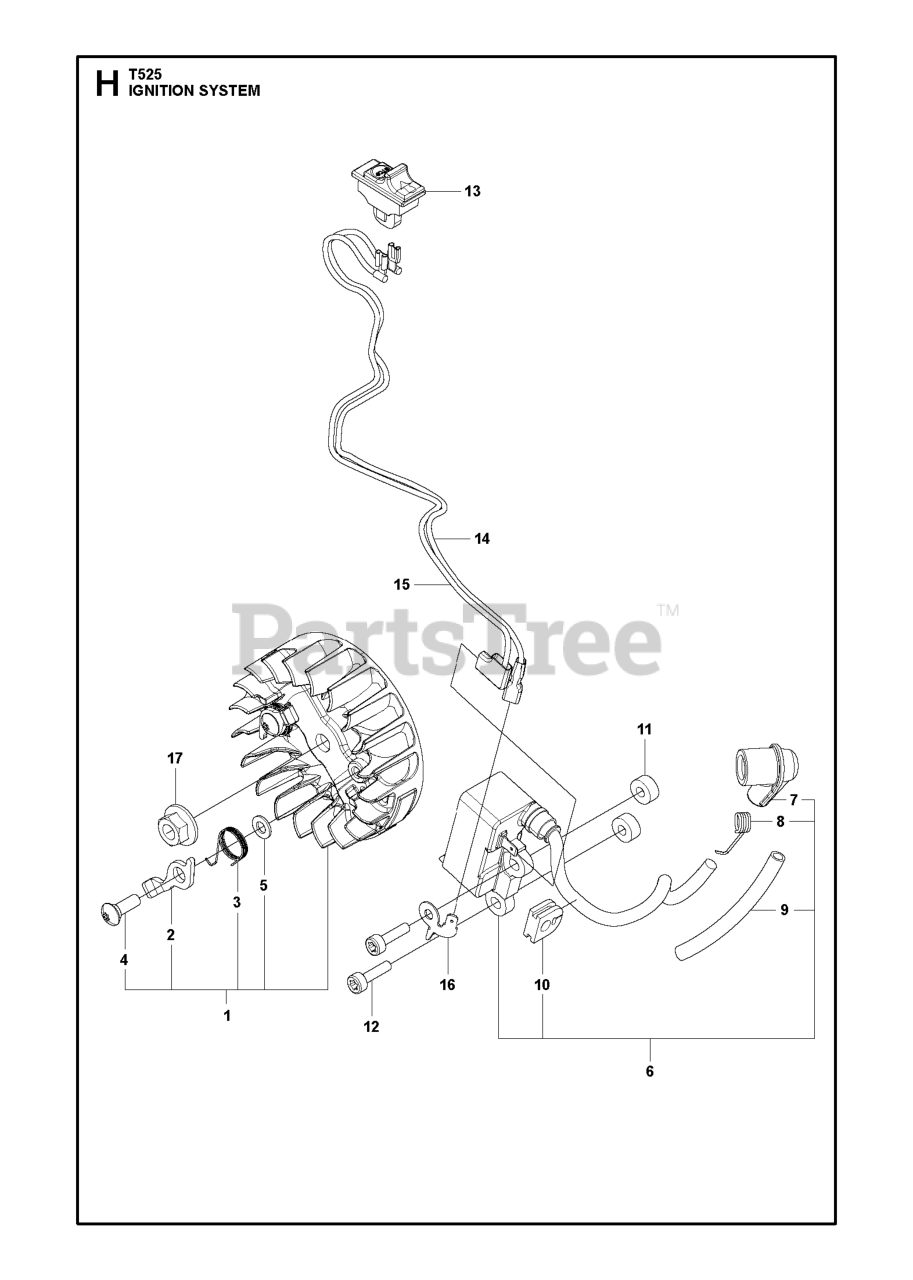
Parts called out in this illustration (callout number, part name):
1	FLYWHEEL ASSY
2	PAWL 848C1471R1
3	SPRING 848C1471S0
4	SCREW 8488151200
5	WASHER 5X10X10
6	IGNITION MODULE ASSY
8	SPRING PLUG
10	GROMMET
13	STOP SWITCH
14	SHORT CIRCUIT CABLE EARTH
15	SHORT CIRCUIT CABLE SWITCH
17	NUT
